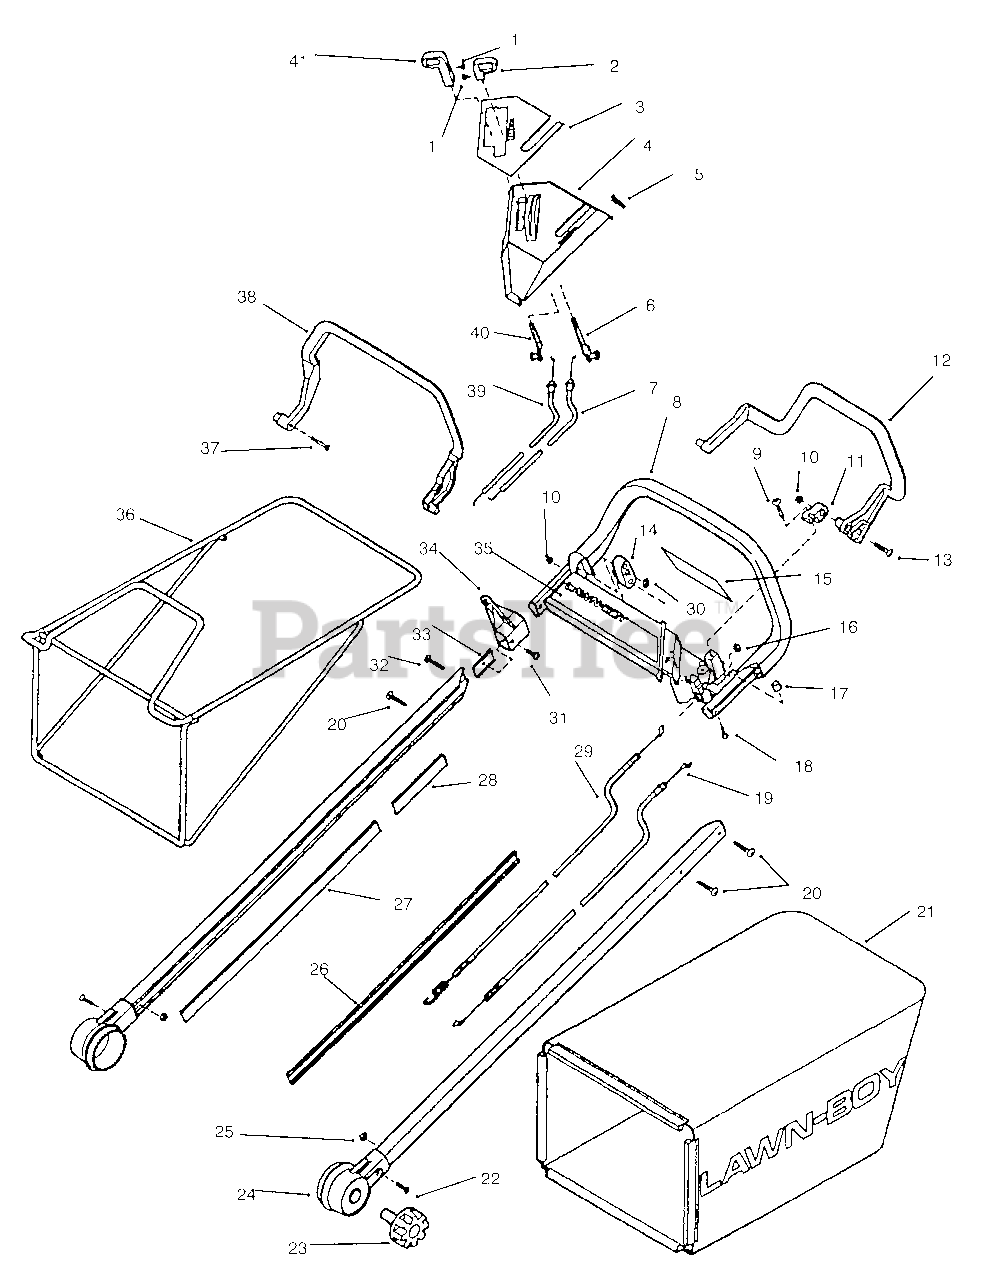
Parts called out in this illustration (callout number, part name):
1	Screw-Set
2	Assembly-Knob, Throttle (Incl. Ref. #1)
4	Assembly-Cover, Upper (Incl. Ref. #3)
6	Lever-Throttle
7	Assembly-Cable, Throttle
8	Assembly-Handle & Decal (Incl. Ref. #15,20 & 35)
11	Pivot-Bail
12	Bail-Self-propelled
14	Block-Bail
15	Decal-Warning
16	Nut-Cable, Self-propelled
19	Assy.-Cable, Eng. Brake
20	Screw-Thread Forming
23	Knob-Mounting, Handle
24	Assembly-Shaft, Handle (Incl. Ref. #23 & 25)
26	Insert-Handle, Cable Side
27	Insert-Handle
28	Insert-Handle
29	Assy.-Cable, Self-propelled
33	Plate-Nut
34	Guide-Rope
35	Decal-Lawn-Boy
38	Bail-Brake, Engine
39	Assy.-Cable, Gear Select
40	Lever-Gear, Select
41	Assy.-Knob, Gear Select (Incl. Ref. #1)
